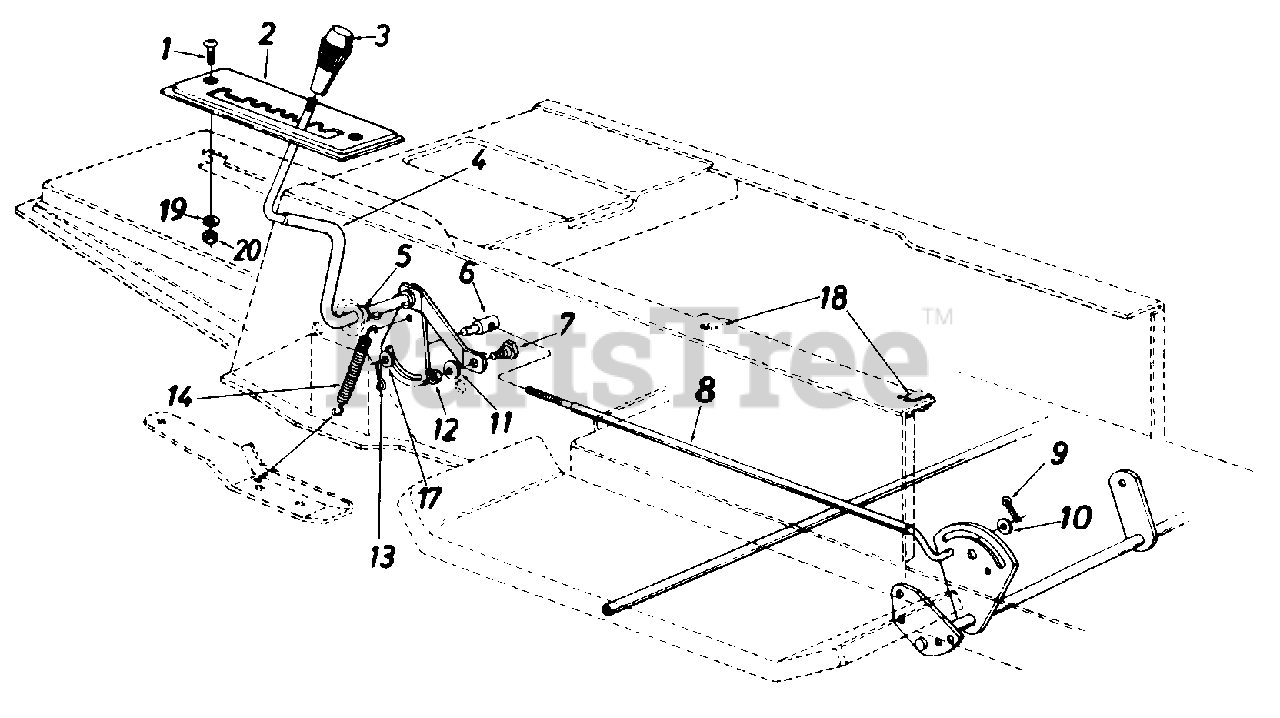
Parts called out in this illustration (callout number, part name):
1	Truss Mach. Scr. 1/4-20 x .75" Lg.
2	7 0 Speed Selector Plate
4	Speed Selector Cam Ass'y.
5	Flat Washer .53" I.D. x .93"
6	Ferrule 3/8-24 x .37" Dia.
7	Shoulder Bolt
8	Speed Control Link
9	Cotter Pin 3/32" Dia. x .75"
10	Fl-Wash. .469" I.D. x .88"
11	L-Wash. 5/16" I.D.
12	Hex Nut 5/16-18 Thd.
13	Cotter Pin 3/32" Dia. x .75"
14	Spring .38" O.D. x 3.18" Lg.
17	Fl-Wash. .385" I.D. x .62"
19	L-Wash. 1/4" I.D.
20	Hex Nut 1/4-20 Thd.
